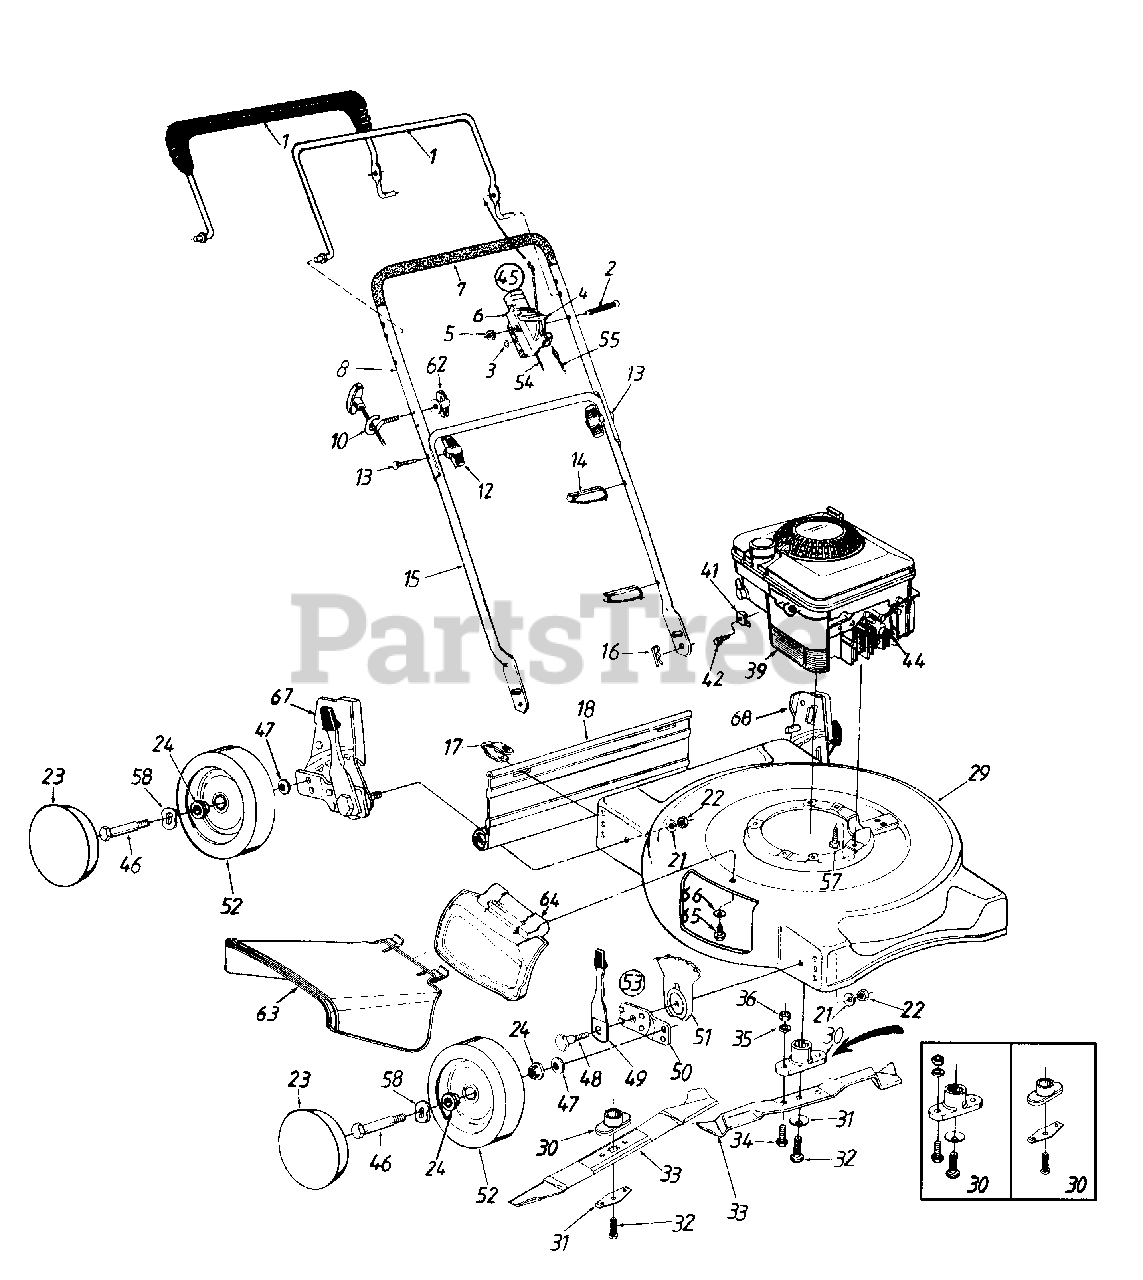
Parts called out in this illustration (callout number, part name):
1	Control Handle Ass'y. Deluxe
2	Oval C-Sunk Scr.
3	Spr. Wash. .66" I.D.
4	Throttle Lever
5	Hex L-Nut 1/4-20 Thd.
6	Throttle Body
12	Hand Knob
13	Curved Hd. Bolt 5/16-18 x 2" L
14	Cable Tie
16	Hairpin Cotter
17	Hinge Clip
18	Rear Flap
21	Bell-Wash. .39" I.D. x 1.38"
22	Hex Nut 3/8-16 Thd.
23	Hub Cap
24	Ball Bearing
29	20" Deck Ass'y.
30	Blade Adapter Kit
31	Bell-Wash. .39" I.D.
31	Support, Blade Bell
32	Hex Bolt 3/8-24 x 1.5" Lg.
33	20" Mulching Blade
34	Hex Bolt 3/8-24 x 1" Lg.
35	L-Wash. 3/8" I.D.
36	Hex Nut 3/8-24 Thd.
39	Engine, Tecumseh
41	Cable Clamp
42	Sems Scr. #10-32 x .38" Lg.
44	Spark Plug Boot
45	Throttle Box Comp.
46	Axle Bolt
47	Bell-Wash. .400" I.D. x .88"
48	Shld. Bolt .50" Dia. x .357"
49	Spring Lever Ass'y. w/Knob
51	Height Adj. Plate
52	Wheels w/o Bearings (Gray - no Hub Cap)Bar Tread
52	Wheels w/o Bearings (Gray) Bar Tread
52	Wheels w/Ball Bearings (Gray) "S" Wave Tread
53	Height Adj. Ass'y. Comp.-R.F.
53	Height Adj. Ass'y. Comp.-L.F.
54	Throttle Cable-39"
55	Control Cable-49"
57	Hex L-Wash. Hd. Scr. 3/8-16 x 1.0" Lg
58	Wave Washer .51" I.D. (Used w/Ball Bearings)
62	Handle Knob 1/4-20 Thd.
63	Chute Deflector
64	Mulching Plug
65	Hex Wash. Hd. TT-Tap Scr. 1/4-20 x .5" Lg.
66	Bell-Wash. 1/4" I.D.
